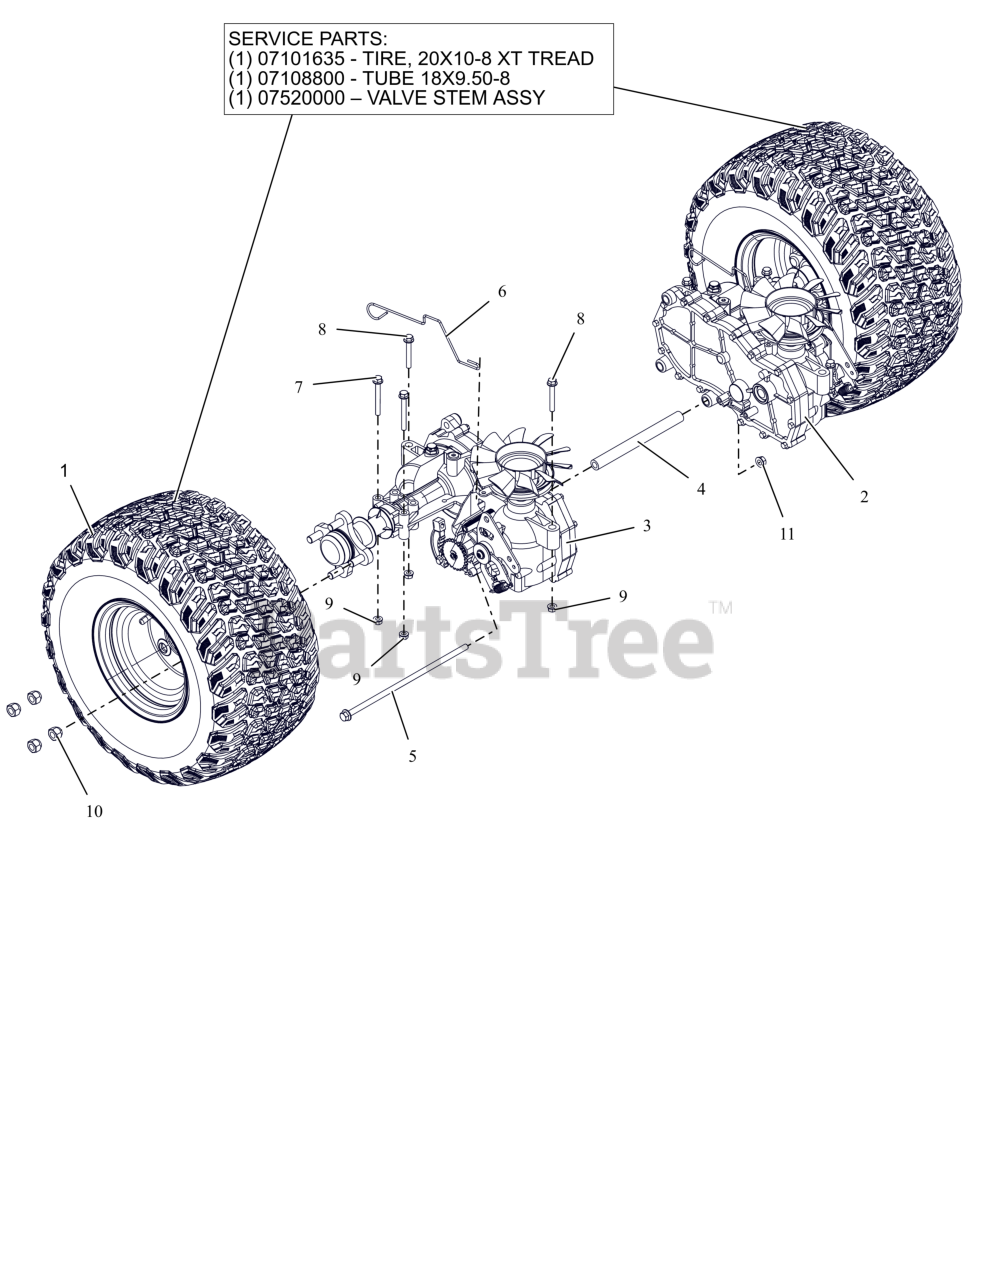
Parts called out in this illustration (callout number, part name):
1	ASM, TIRE /WHL 20X10-8 XT TREAD
1	TIRE, 20X10-8 XT TREAD
1	TIRE TUBE 18/6.50/8.50/9.50-8, 20/8.00/10.00-8 4 PLY TR13 STRAIGHT VALVE
1	VALVE STEM ASS'Y
2	TRANSAXLE- EZT - LH
3	TRANSAXLE- EZT-RH
4	TUBE, TRANSAXLE BRACE 8.18LG
5	BLT,HEX-FLG .38-16X11.5 G5 ZCC
6	WIRE- DUMP VALVE LEVER
7	BLT,HEX-FLG .31-18X2.75 G5 ZCC
8	BLT,HEX-FLG .31-18X2.25 G5 ZCC
9	NUT,LK-CTR-FLG .31-18 GF ZCC
10	NUT, WHEEL .50-20 ZCC
11	NUT-LK-CTR-FLG .375-16 GF ZCC
